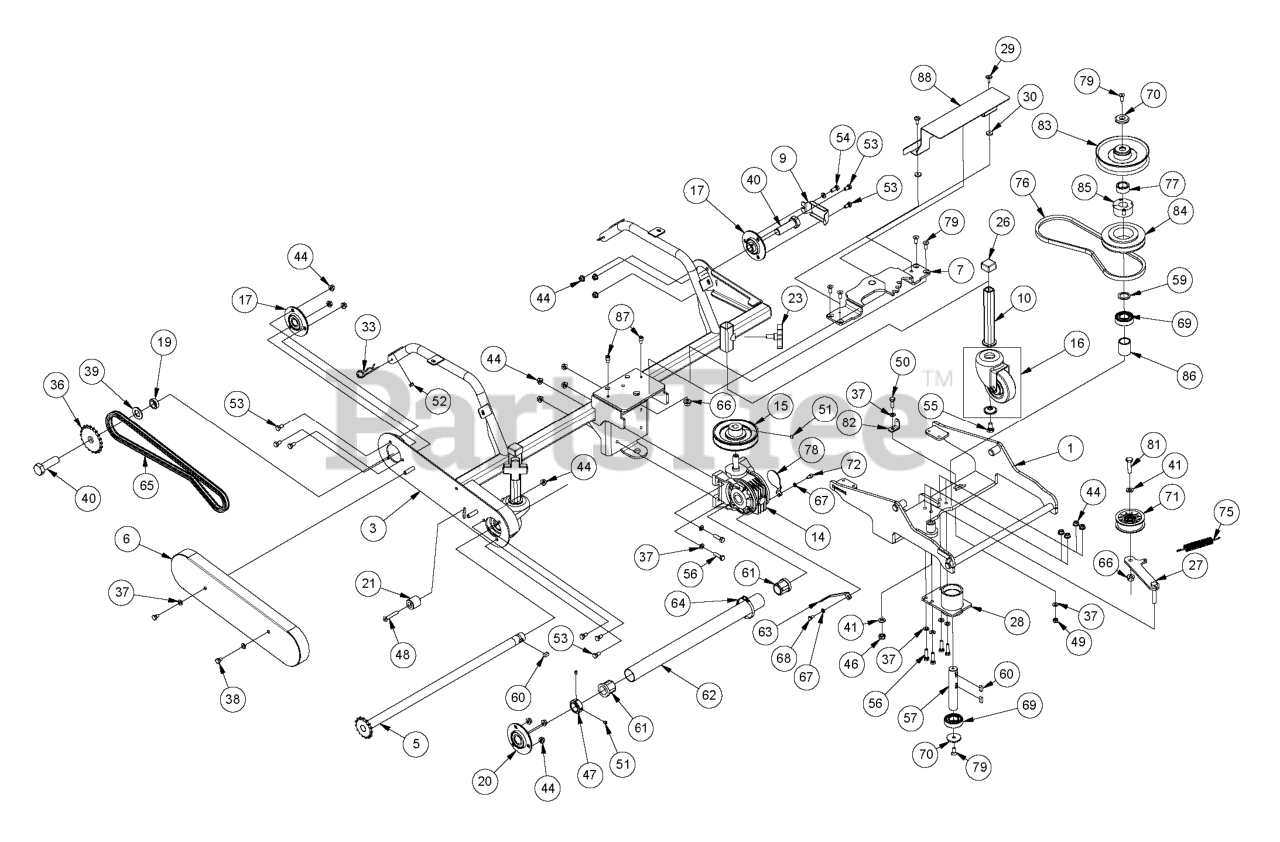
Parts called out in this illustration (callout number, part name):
14	GEAR BOX ASSY
16	SUPPORT WHEEL
21	CHAIN ADJUSTER
23	WINGSCREW
29	SCREW
33	COTTER PIN
36	WHEEL
44	NUT LOCKING
46	NUT
49	NUT
50	SCREW
52	NUT
72	SCREW
87	SCREW
89	DECAL.HUSQVARNA.210MM
